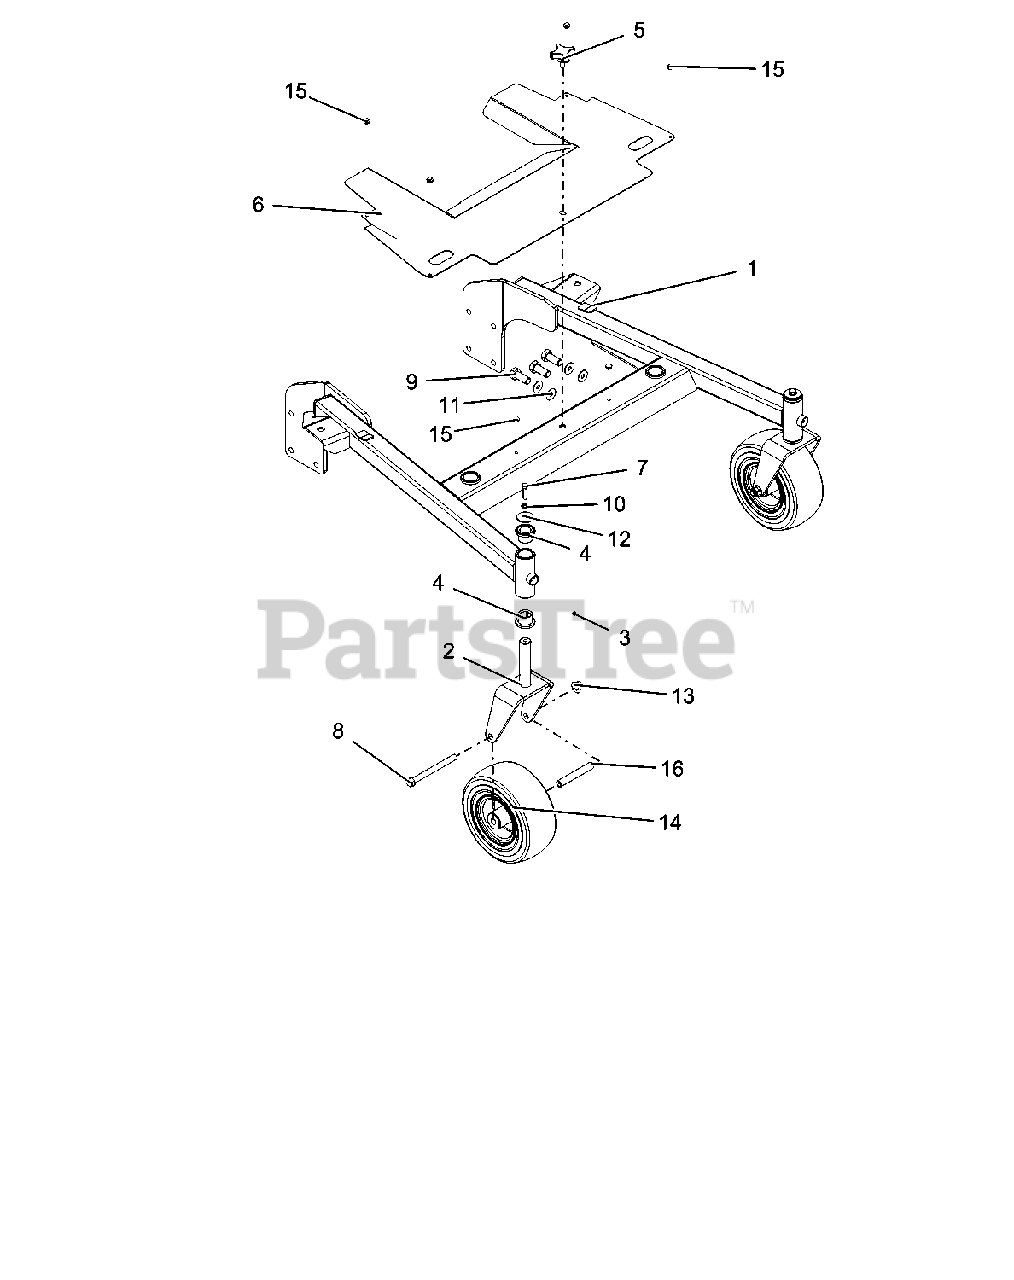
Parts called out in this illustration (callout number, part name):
1	WLDMT, DECK FRAME 52 FLWLK-RED
2	WLDMT, FRONT WHEEL FLOAT WALK
3	FTG, 1/4-28 STRGT GREASE ZERK
4	BRG, FLANGE 1.00 X 1.25 X 1.00
5	KNOB, 3/8-16 x .75
6	SHIELD, BELT 52" HYDRO WALK
7	BLT-HEX .38-16X1.25 GR5 YWZC
8	BLT-HEX .50-13X5.50 GR5YWZC
9	BLT-HEX .62-11X1.50 GR5 YWZC
10	WSHR-LK .38X.094 REG YWZC
11	WSHR-FL-STL .375X1.125X.065YWZ
12	WSHR-FL-STL .380X1.50X.125 YWZC
13	NUT-LK-NYL-FLG .50-13 YWZC
14	9X3.5-4 CAREFREE BLT TOGETHER
15	BUMPER GROMMET .125 X .25 REV
16	TUBE, CASTER AXLE
